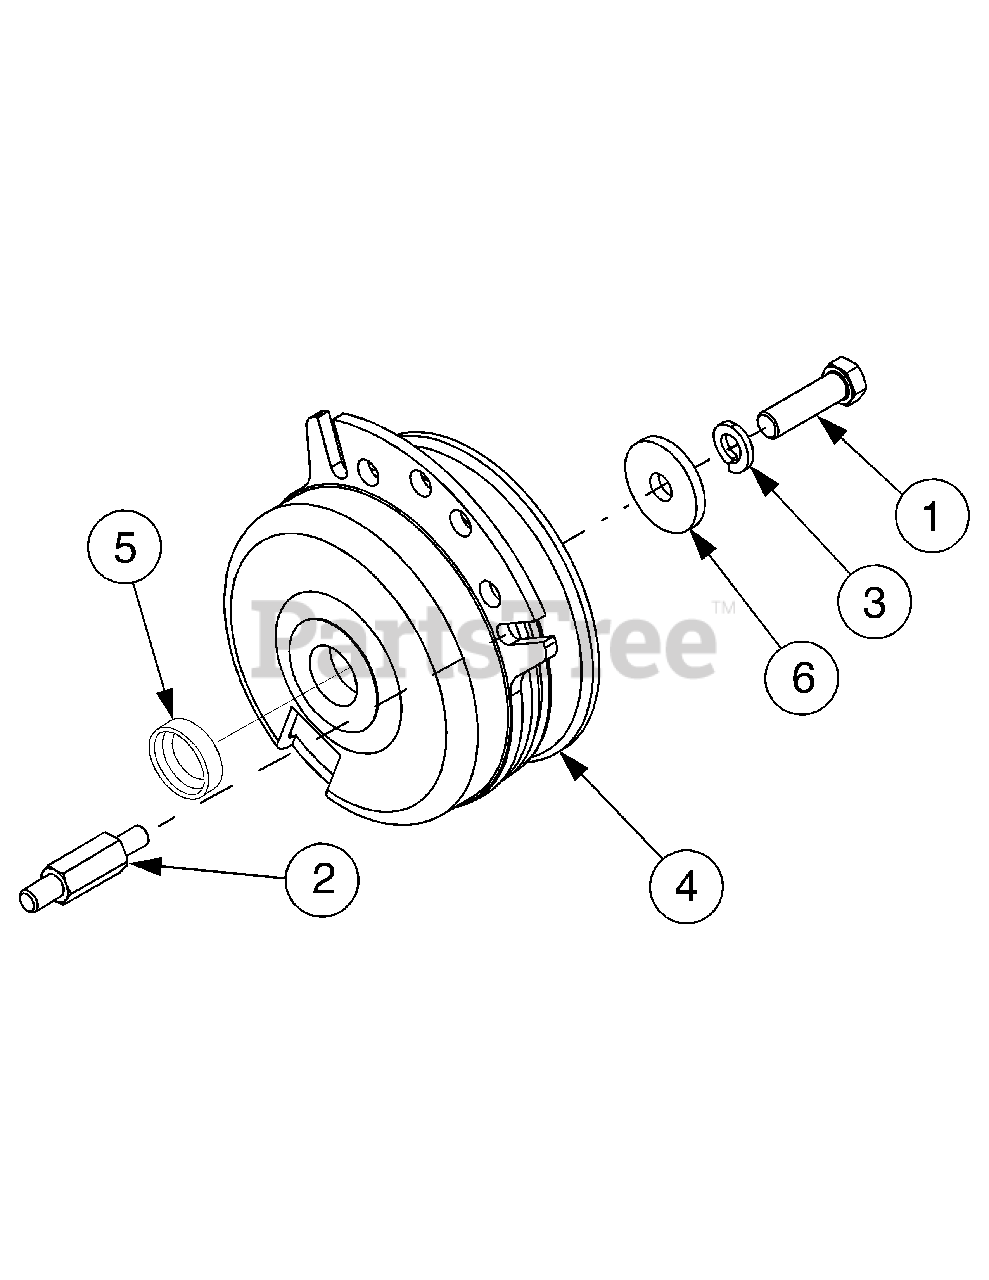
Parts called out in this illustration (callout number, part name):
1	Screw, Hex Cap, 7/16-20 x 1.5 GR5
2	Stud, Clutch Stop (S.N. K016 and Before)
2	Stud, Clutch Stop (S.N. K016 and After)
3	Washer, Lock, 7/16
4	Clutch Assy, PTO
5	Spacer, 1.0 x 1.62 x .4
6	Washer, Flat, .445 x 1.5 x 1.72 Hdn
